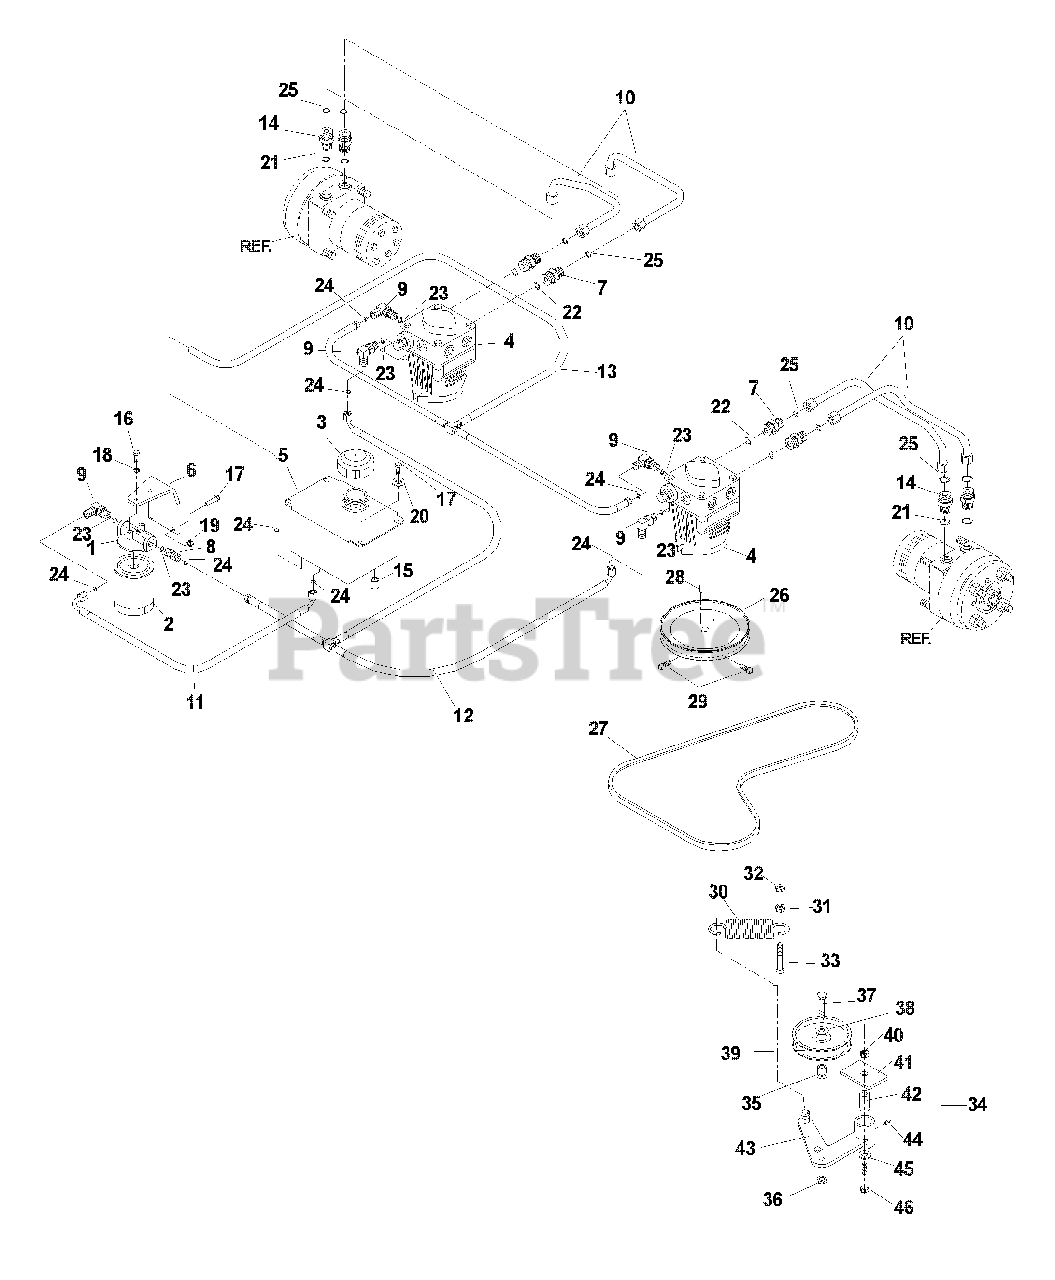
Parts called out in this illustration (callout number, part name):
1	FILTER HEAD
3	CAP HYDRAULIC RESERVOIR
4	PUMP
6	BRACKET, OIL FILTER
7	FITTING, STRAIGHT, F6400-8-8-0
8	FITTING, F6400-6-6-0
9	FITTING, 90°, F6801-6-6-0
10	HYDRAULIC LINE
12	"T" ASSEMBLY
13	"T" ASSEMBLY
14	FITTING, STRAIGHT
16	HCS 1/4C X 5/8
17	HCS 1/4C X 3/4
18	LOCKWASH, 1/4
19	NUT, 1/4C, NYLOC
20	WASHER, 1/4, FLAT
21	"O" RING, 3/4
22	"O" RING, 1/2
23	"O" RING, 3/8
24	"O" RING FLARE, 3/8
25	"O" RING FLARE, 1/2
26	PULLEY, PUMP
27	BELT, PUMP
28	KEY, 5 MM SQ. X 25 MM
29	SET SCREW, 5/16C X 5/8
31	NUT, 3/8C, WHIZ
32	NUT, 3/8C, NYLOC
33	HCS, 3/8C X 2
34	IDLER ARM ASSEMBLY
35	IDLER FLANGE BUSHING
36	NUT, 3/8C, CENTERLOCK
37	HCS, 3/8C X 1 3/4
38	WASHER, 3/8
39	IDLER PULLEY
40	NUT, 1/2C, NYLOC
41	SUPPORT PLATE
42	PIVOT BUSHING
43	IDLER ARM
44	ZERK
45	WASHER, 1/2
46	HCS, 1/2C X 3 1/4, GR5
